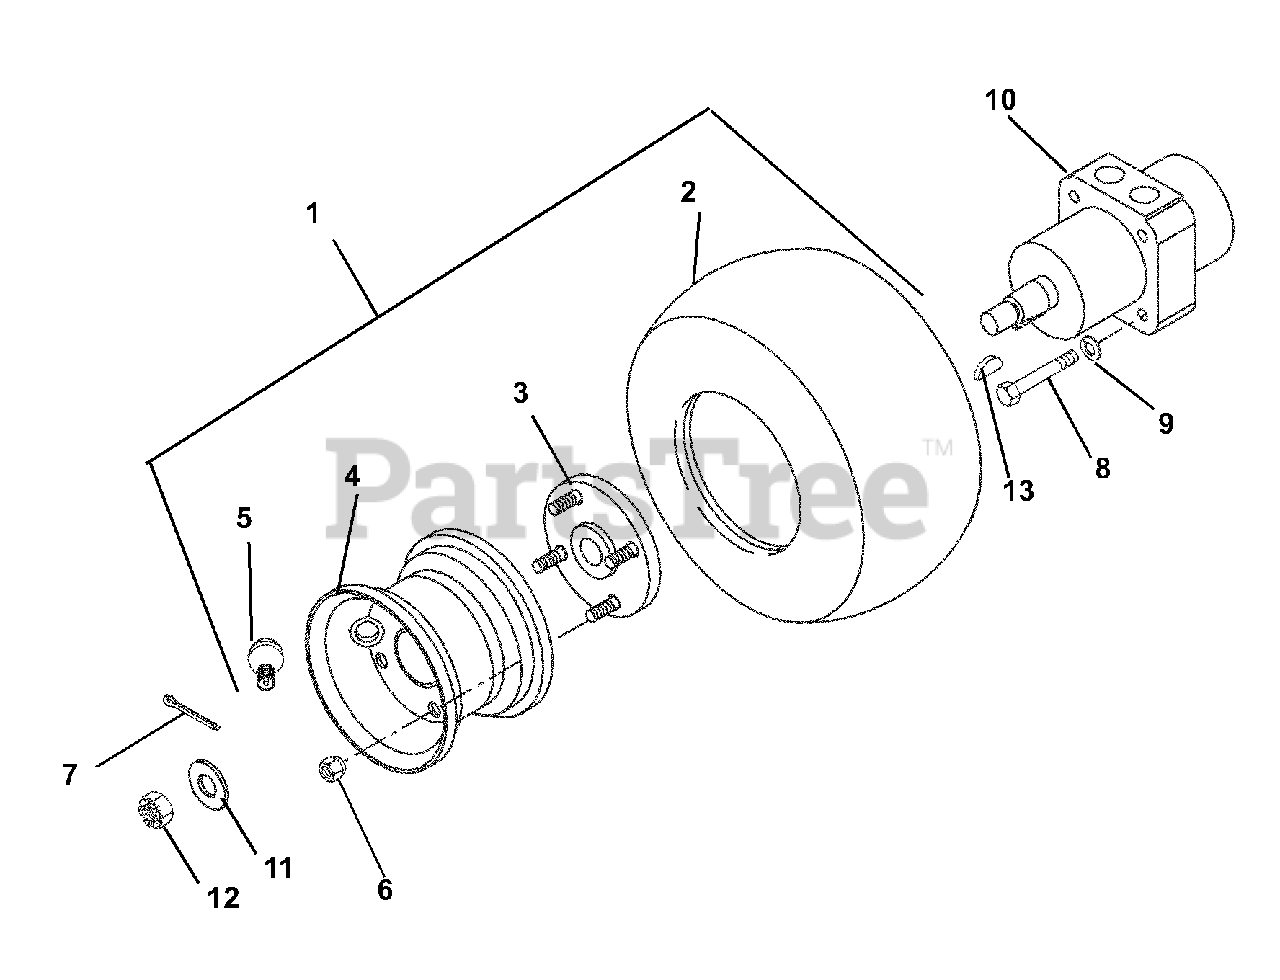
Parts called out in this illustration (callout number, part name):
1	Assembly, Tire and Wheel
2	Tire 18 x 8.50 - 8
3	Assembly, Hub
4	Assembly, Rim
5	Valve Stem Assembly
6	Nut, Lug .50-20
7	Pin, Center .12 x 1.25
8	Bolt, Hex .38-16 x 1.00 Grade 5
9	Washer, Locking .38 x .094 Regular
10	Motor, Hydraulic Wheel
11	Washer, Flat Steel .812 x 1.50 x .135
12	Nut, Hex .75-28 Slotted
13	Key, Woodruff .19 x .75
